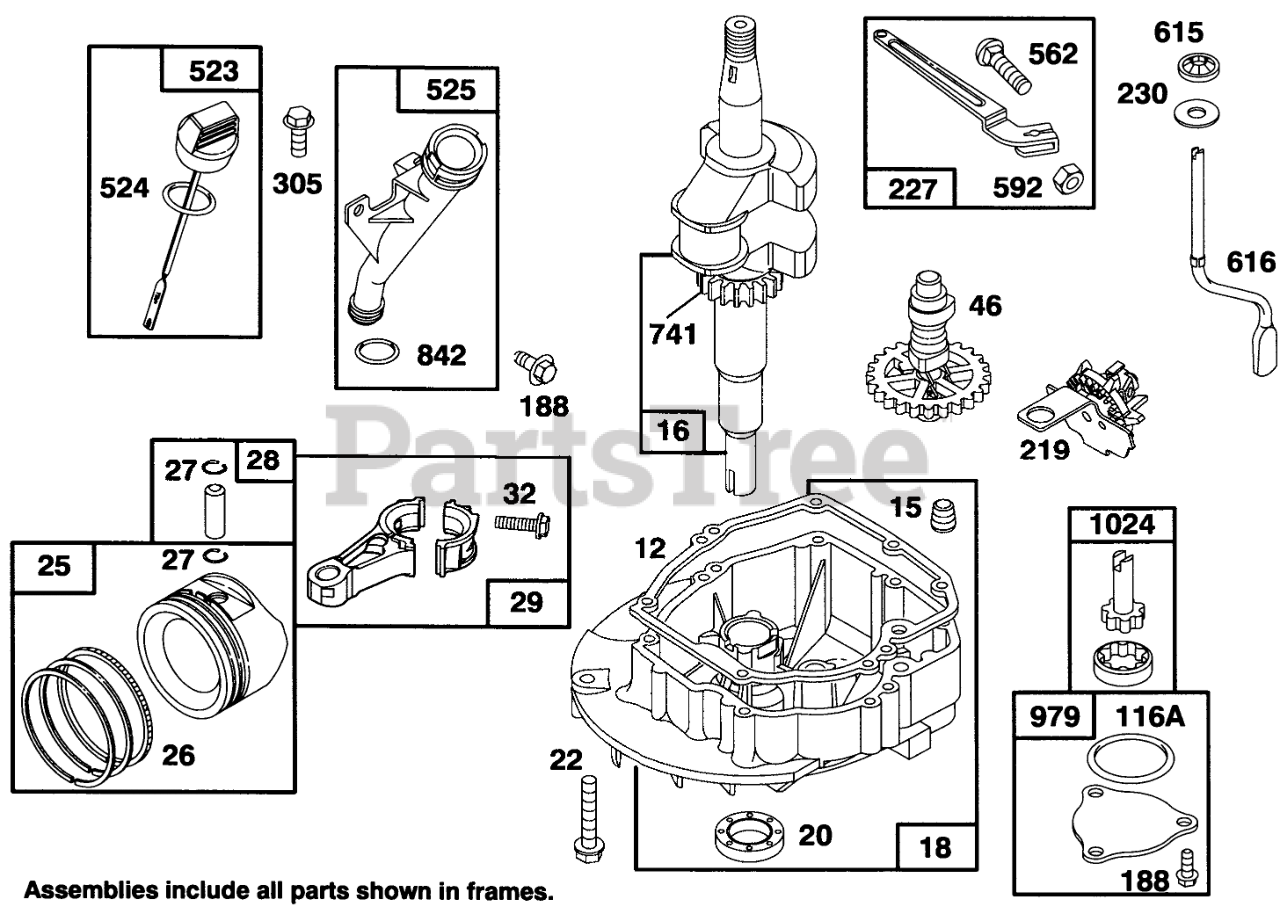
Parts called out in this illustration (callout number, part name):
12	ENGINE BASE GASKET
15	PIPE PLUG
16	CRANKSHAFT
18	ENGINE SUMP
20	SEAL-OIL
22	SCREW - ENGINE BASE
25	STD PISTON ASSEMBLY
26	STD RING SET
27	PISTON PIN LOCK
28	Pin Assy-Piston
29	CONNECTING ROD
32	Connecting Rod
46	CAM GEAR
116A	O RING SEAL
188	SCREW - SEM
219	GOVERNOR/OIL SLINGER
227	GOVERNOR LEVER ASSEMBLY
230	WASHER
305	SCREW - HEX HEAD
523	DIPSTICK-OIL
524	O-RING
525	OIL FILLER TUBE
562	GOVERNOR LEVER BOLT
592	HEX NUT
615	FASTENER
616	GOVERNOR CRANK
741	TIMING GEAR
842	O-RING
979	OIL PUMP COVER
1024	OIL PUMP
